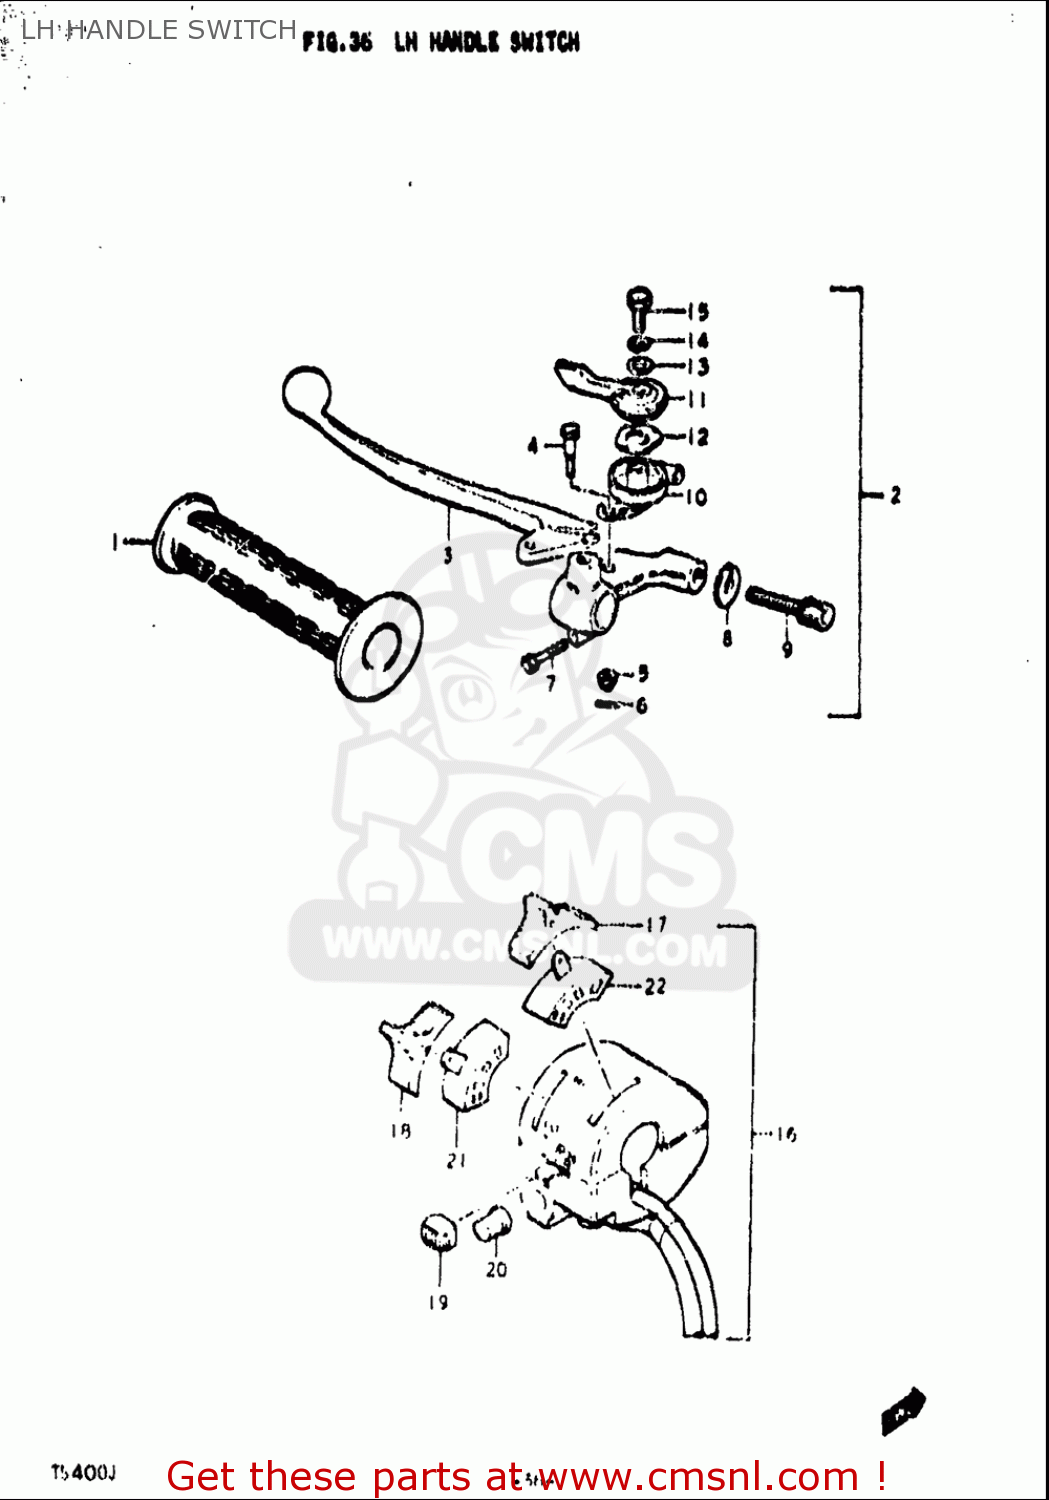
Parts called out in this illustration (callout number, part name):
1	GRIP
3	LEVER,CLUTCH
4	BOLT,LEVER PIVOT
5	NUT,LEVER FITTNG
6	PIN 16X20
7	BOLT
8	NUT,CABLE ADJUSTER
9	ADJUSTER,CABLE
11	LEVER
12	WASHER,ADJUSTER
13	WASHER(6.5X16X1)
14	WASHER,LOCK
15	BOLT
19	KNOB,HANDLE SWITCH
20	BUTTON, HORN
21	SLIDING BLOCK, DIMMER SWITCH
